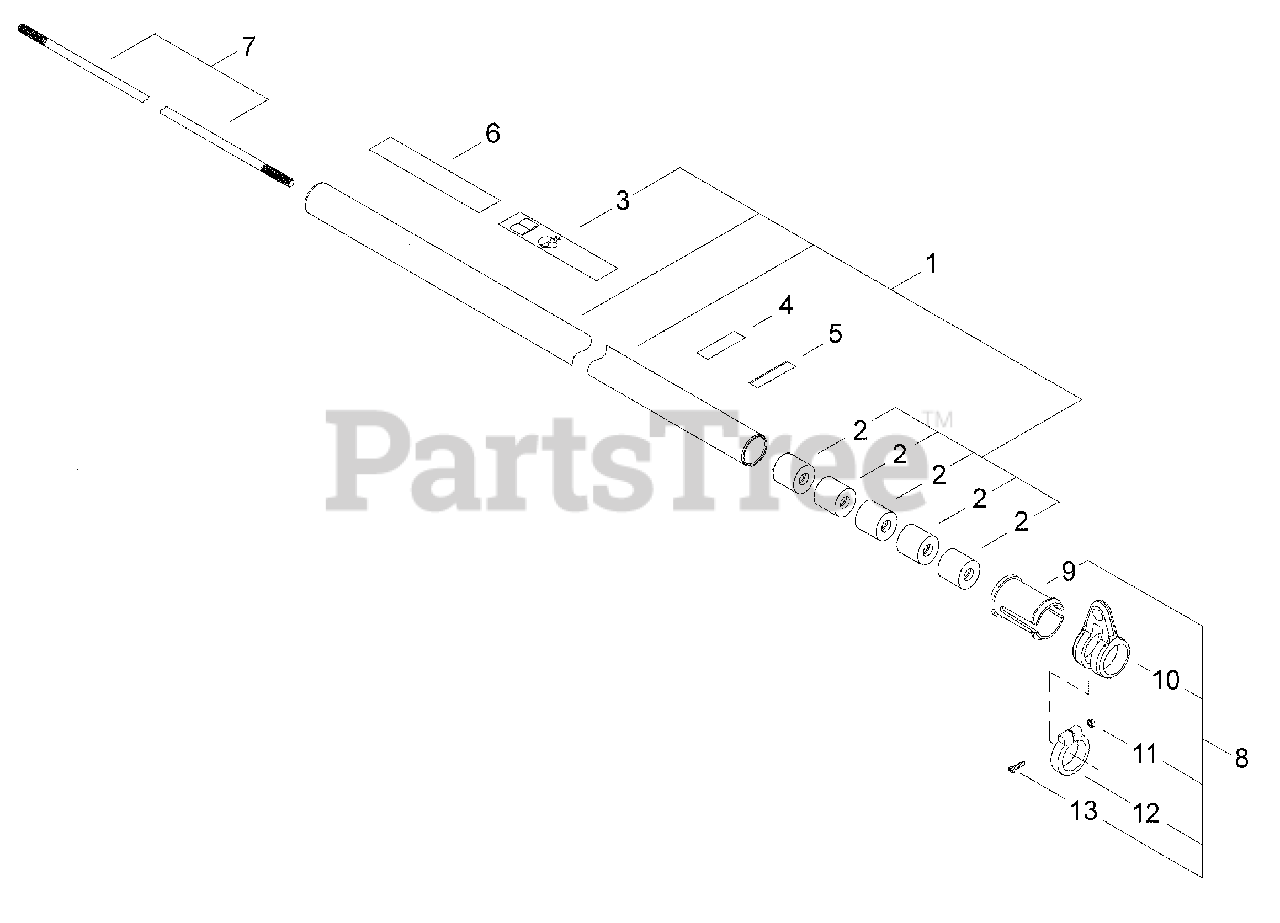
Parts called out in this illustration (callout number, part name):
1	OUTER TUBE ASSY
2	BUSHING
3	LABEL - CAUTION
4	LABEL - INSTRUCTION
5	LABEL - HANDLE LOCATION
6	LABEL - SWISHER E4
7	PIPE, MAIN
8	HANGER ASSY
9	COLLAR
10	HANGER
11	NUT - 4
12	CLAMP
13	SCREW - 4X16
